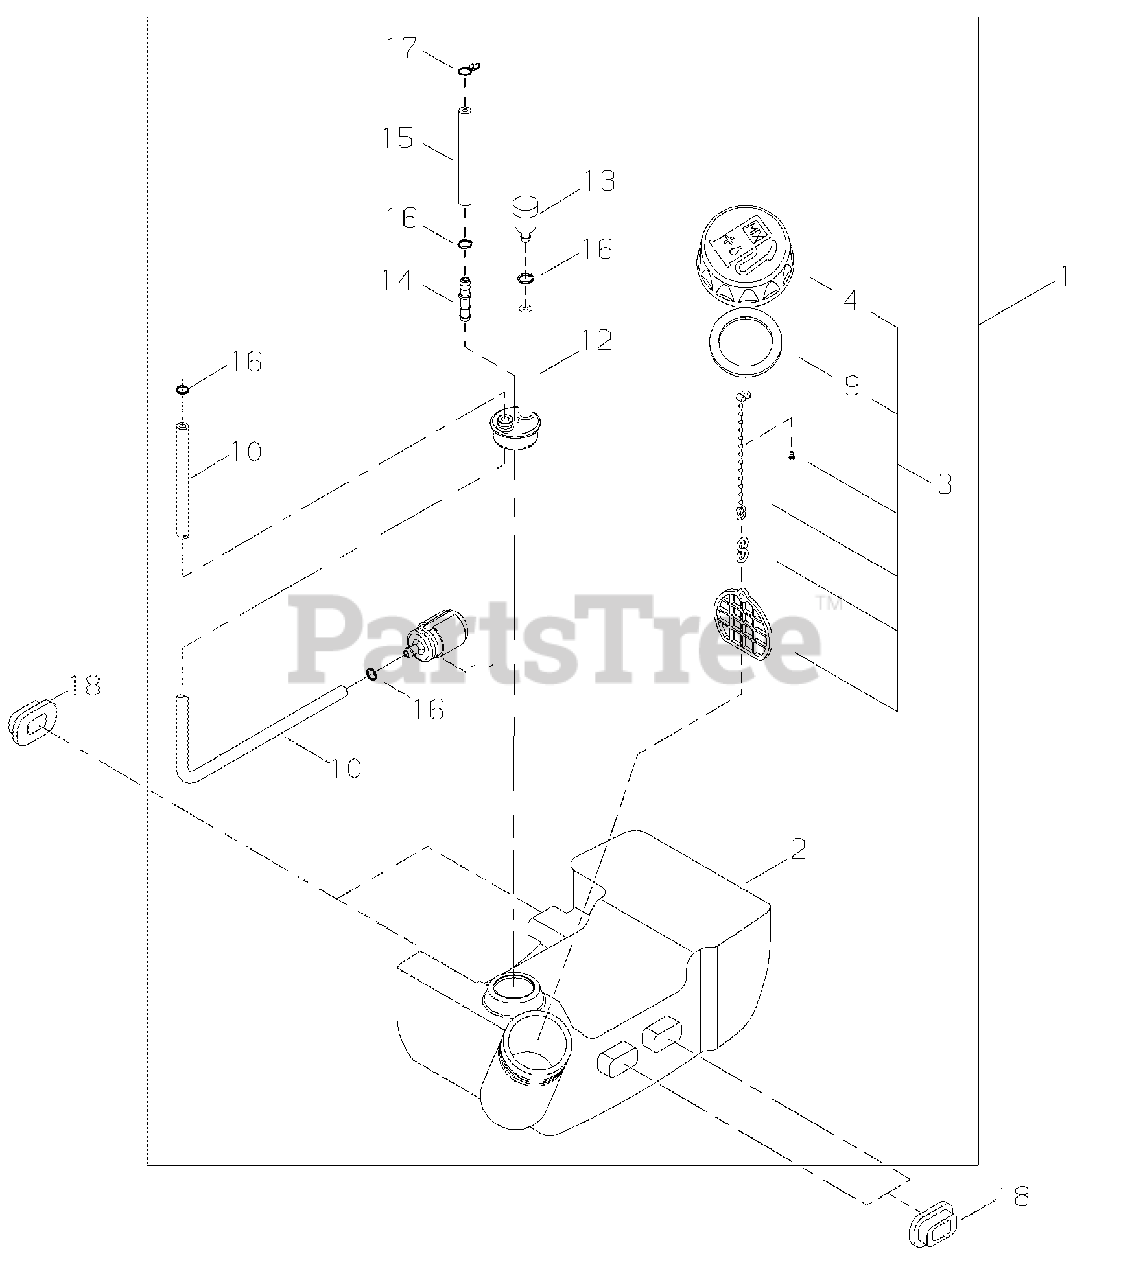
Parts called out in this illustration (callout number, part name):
1	TANK ASSY, FUEL
2	TANK, FUEL
3	CAP ASSY, FUEL
4	CAP, FUEL
9	GASKET, FUEL CAP
10	PIPE, FUEL
11	FILTER, FUEL 125-528
12	GROMMET, FUEL W/VENT PIPE
13	VENT ASSY
14	CONNECTOR, PIPE
15	PIPE, FUEL RETURN
16	CLIP Ø6
17	CLIP, SPRING Ø5.2
18	CUSHION, FUEL TANK
